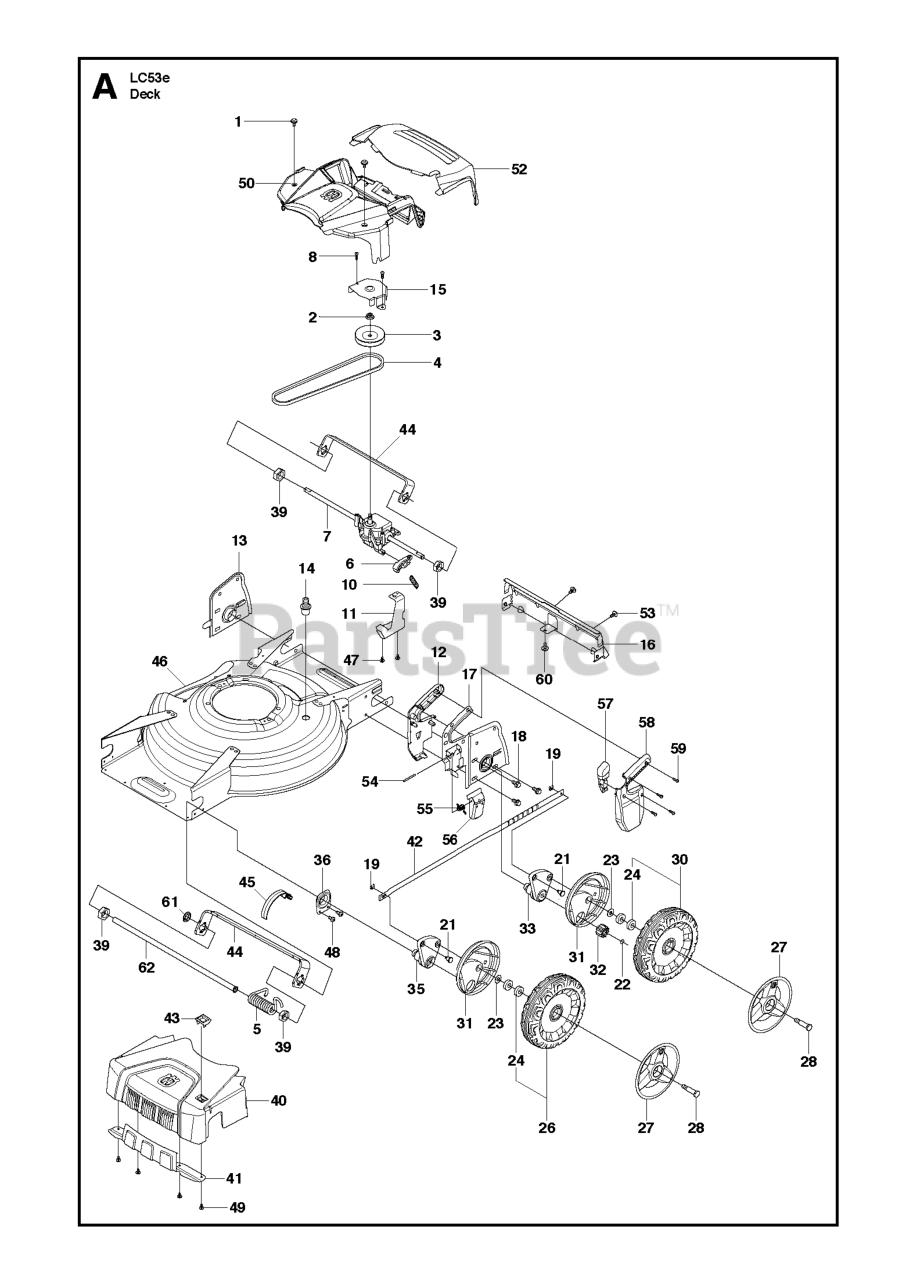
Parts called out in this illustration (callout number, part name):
1	SCREW ITXPANTT M5X10 ZPB (A00
8	SCREW ITXPANT T50X16 ZN/FE (A
19	FASTENER
24	BALL BEARING
47	SCREW ITXPANTT M5X10 ZPB (A00
48	SCREW ITXPANTT M5X10 ZPB (A00
49	SCREW ITXPANTT M5X10 ZPB (A00
53	SCREW ITXPANTT M5X10 ZPB (A00
59	SCREW ITXPANT T50X16 ZN/FE (A
60	SCREW ITXPANTT M5X10 ZPB (A00
